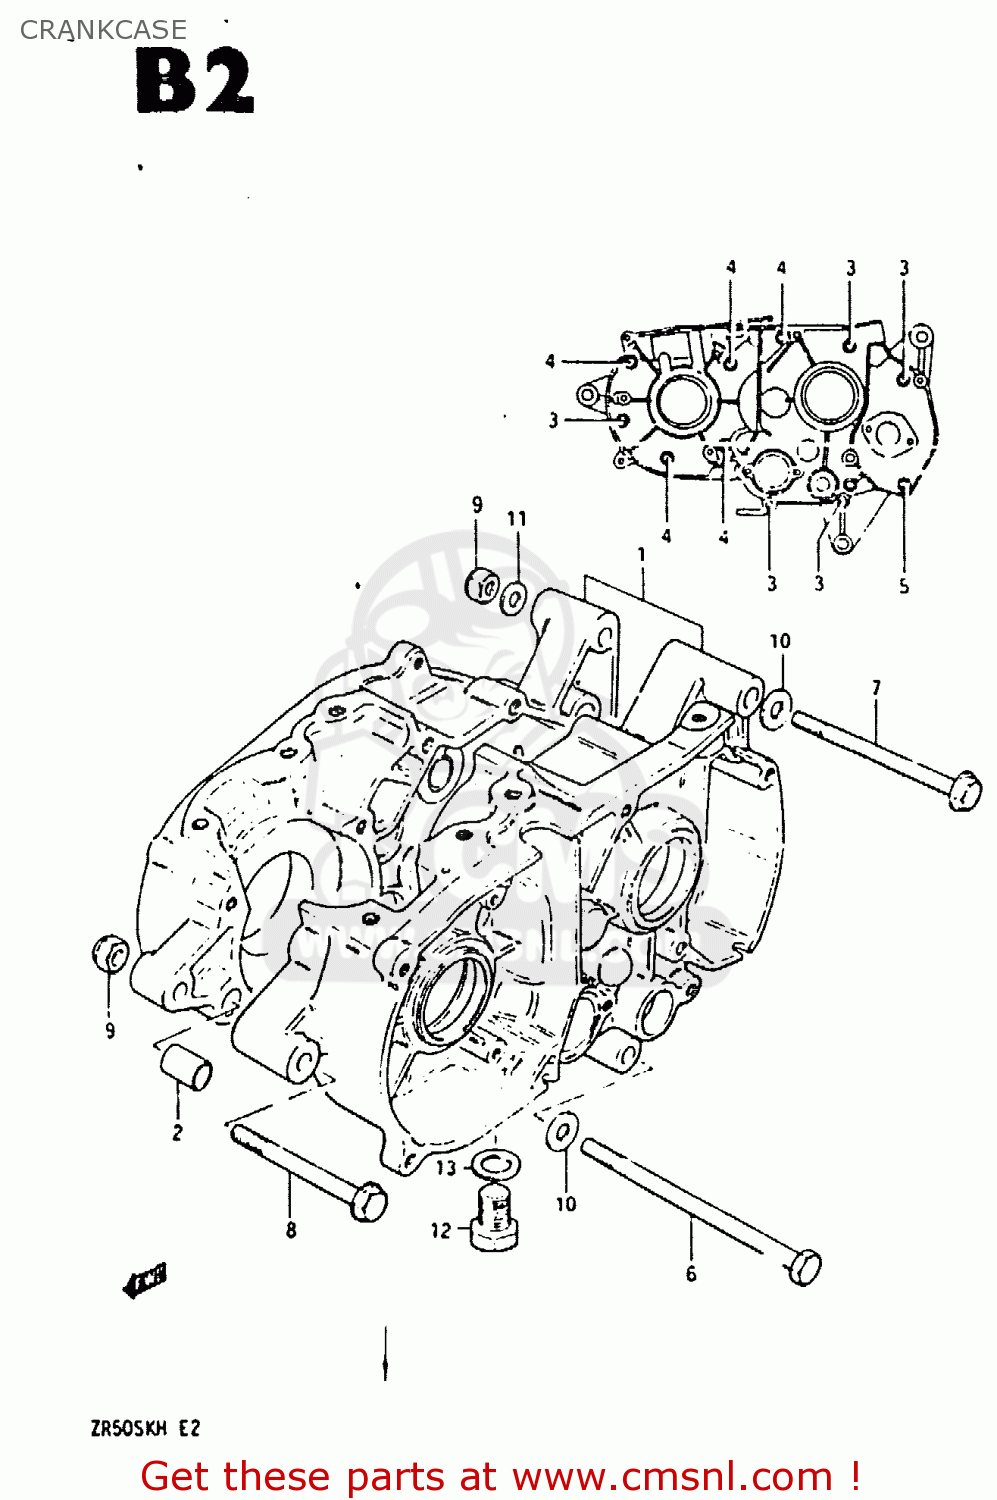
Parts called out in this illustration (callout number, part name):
1	CRANKCASE ASSEMBLY
2	PIN
3	SCREW (6X45)
4	SCREW (6X35)
5	SCREW
6	BOLT 8X115
7	BOLT(8X100)
8	BOLT 8X75
9	NUT
10	WASHER
11	WASHER
12	BOLT 10X20
13	GASKET(10X14X3.6) (NAS)
